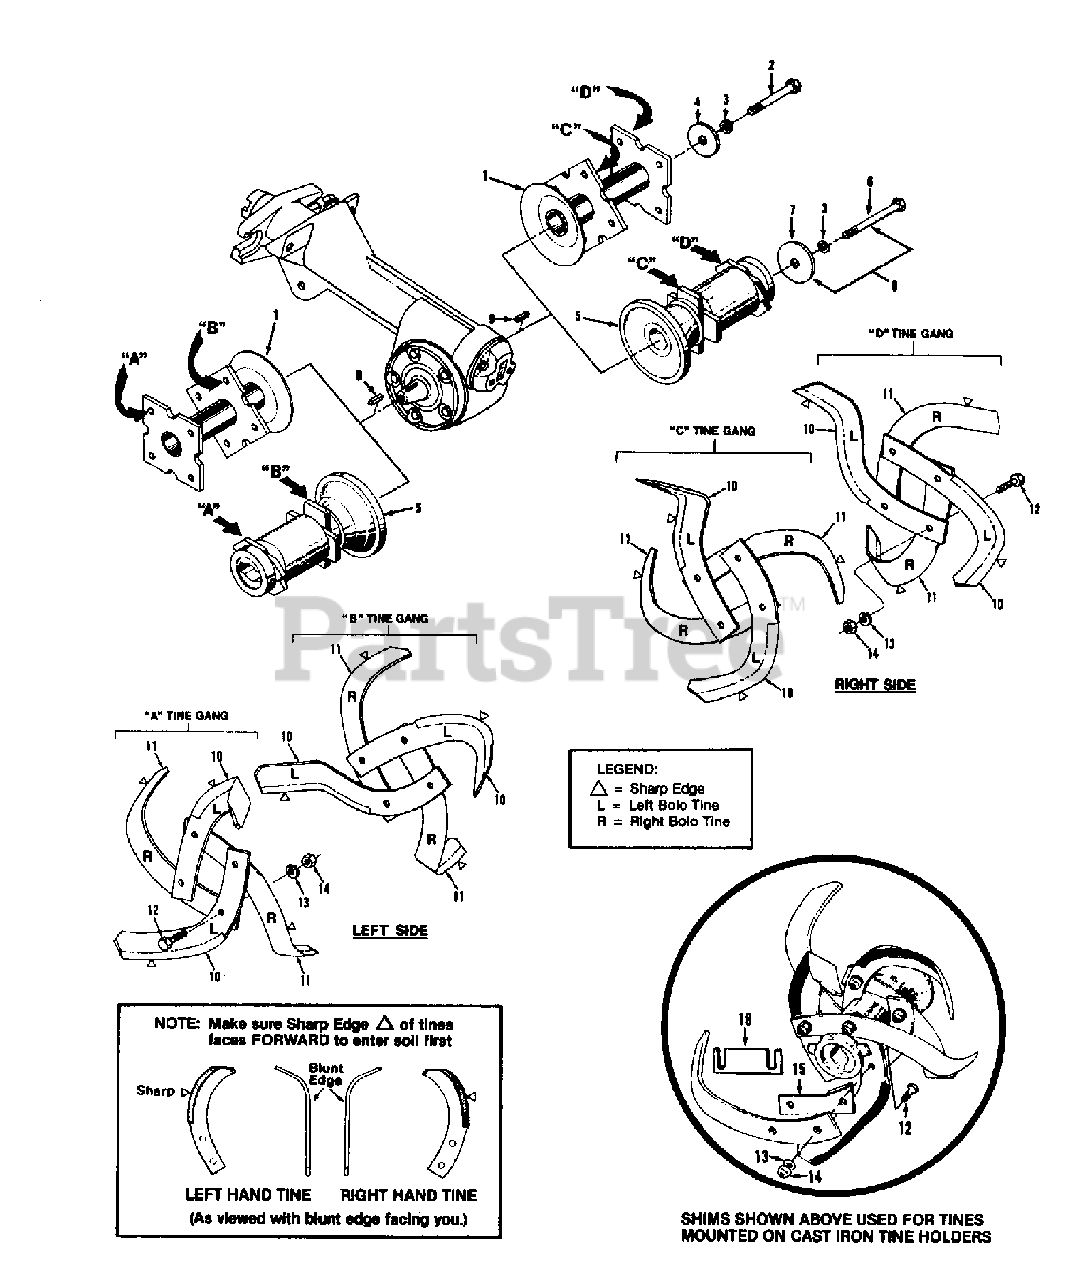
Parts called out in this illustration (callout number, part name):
1	TINE HOLDER- welded steel.
2	BOLT - hex hd., 1/2"-20 x 4-3/4" long. Mounts Part #2415 welded steel tine holder on tine shaft
3	LOCKWASHER-1/2", holder mounting
4	WASHER - flat. Outer dia. 1.500", inner dia. .516",thickness .182".
5	TINE HOLDER - cast iron.
6	BOLT - hex hd.,1/2"-20 x 5-3/4" long. Mounts Part #1205 cast iron tine holder on tine shaft
7	WASHER - flat. Outer dia. 1-3/4", inner dia. 17/32".
8	BOLT 8 WASHER SET -
9	KEY - tine shaft 3/16" square x 1" long
10	BOLO TINE - single, Left Hand.
11	BOLO TINE- single, Right Hand.
12	BOLT - hex hd., 3/8"-16 x 1", tine mounting
13	LOCKWASHER-3/8" tine mounting
14	NUT- hex, 3/8"-16, tine mounting
15	TINE SHIM -
16	TINE SHIM -
